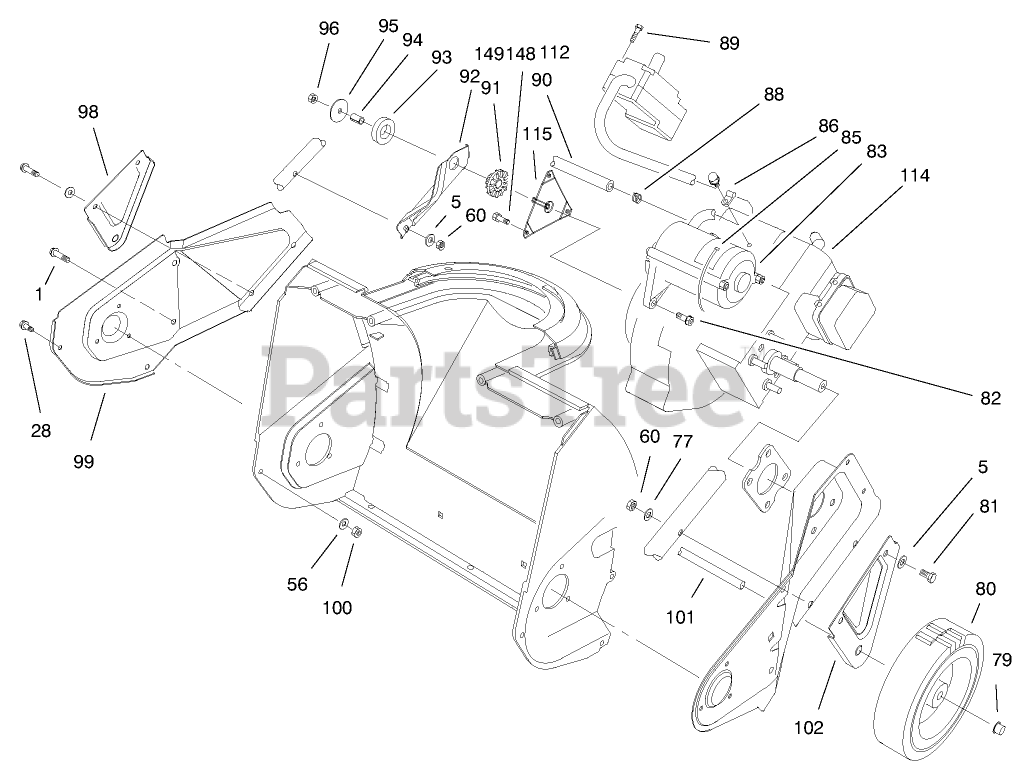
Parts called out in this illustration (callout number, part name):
1	SCREW-PLASTIC
5	WASHER-FLAT
56	WASHER-FLAT
60	NUT-LOCK, NI
77	WASHER
79	RETAINER-PUSH ON
80	WHEEL
81	SCREW-HH
82	SCREW-HH, TORX
83	ASM-Switch Housing
85	TIE-CABLE
86	CLAMP
88	CLAMP-HOSE
89	SCREW-PLASTITE
90	LINE-GAS
91	BUSHING-ISOLATOR
92	Support-Engine
93	Ring-Isolator
94	SPACER-TUBULAR
95	WASHER-FLAT
96	NUT-LOCK, NI
98	Bracket-Wheel
99	Sideplate-RH
100	NUT-LOCK, NI
102	Bracket-Wheel
112	SCREW X
115	BRACKET AND STUD ASM
147	Decal-Plate
148	SCREW
149	WASHER-LOCK / EXT
